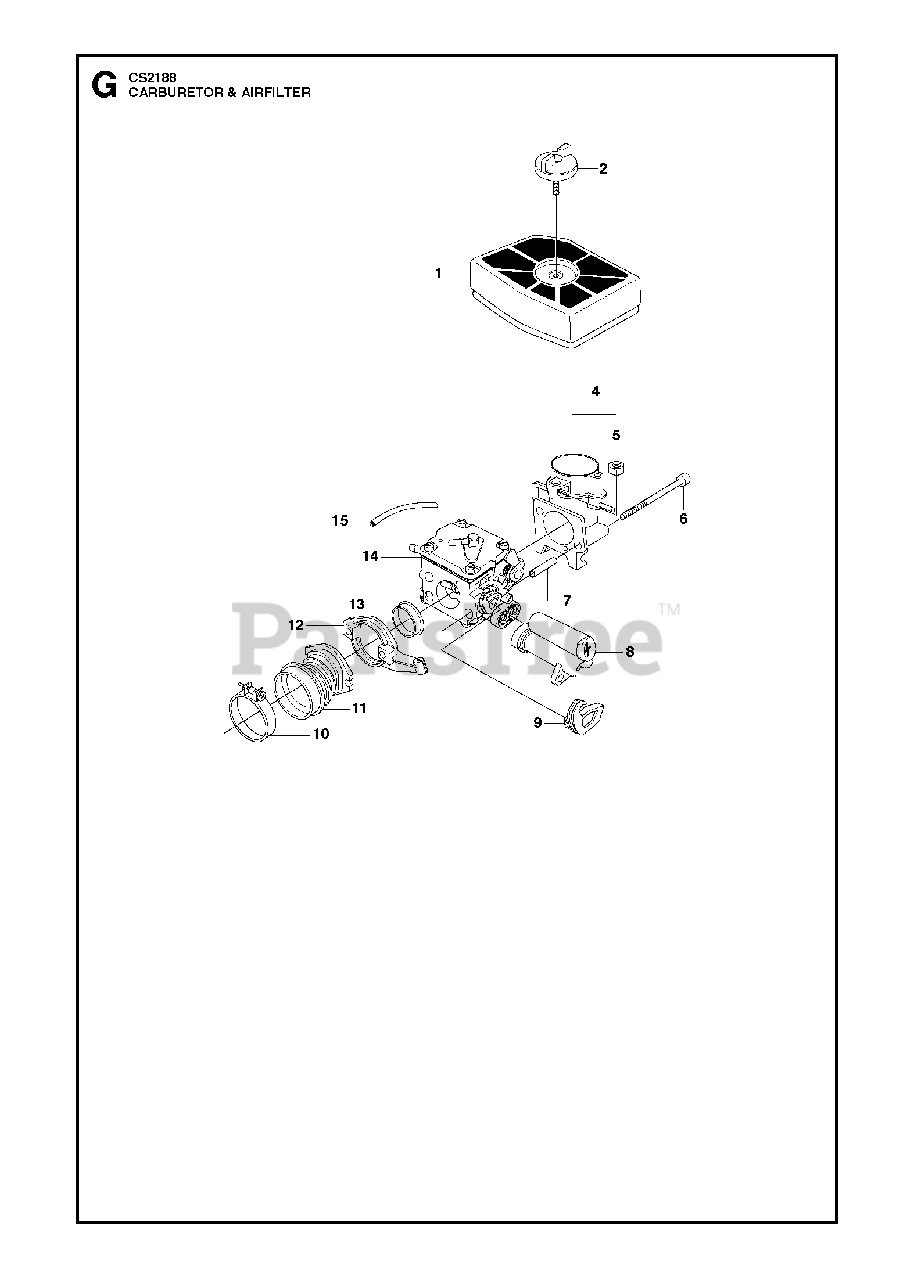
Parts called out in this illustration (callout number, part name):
1	AIR FILTER
4	FILTER HOLDER
5	NUT
8	GUIDE BUSHING
10	CLAMP
11	RP INTAKE PIPE
14	CARBURETOR
